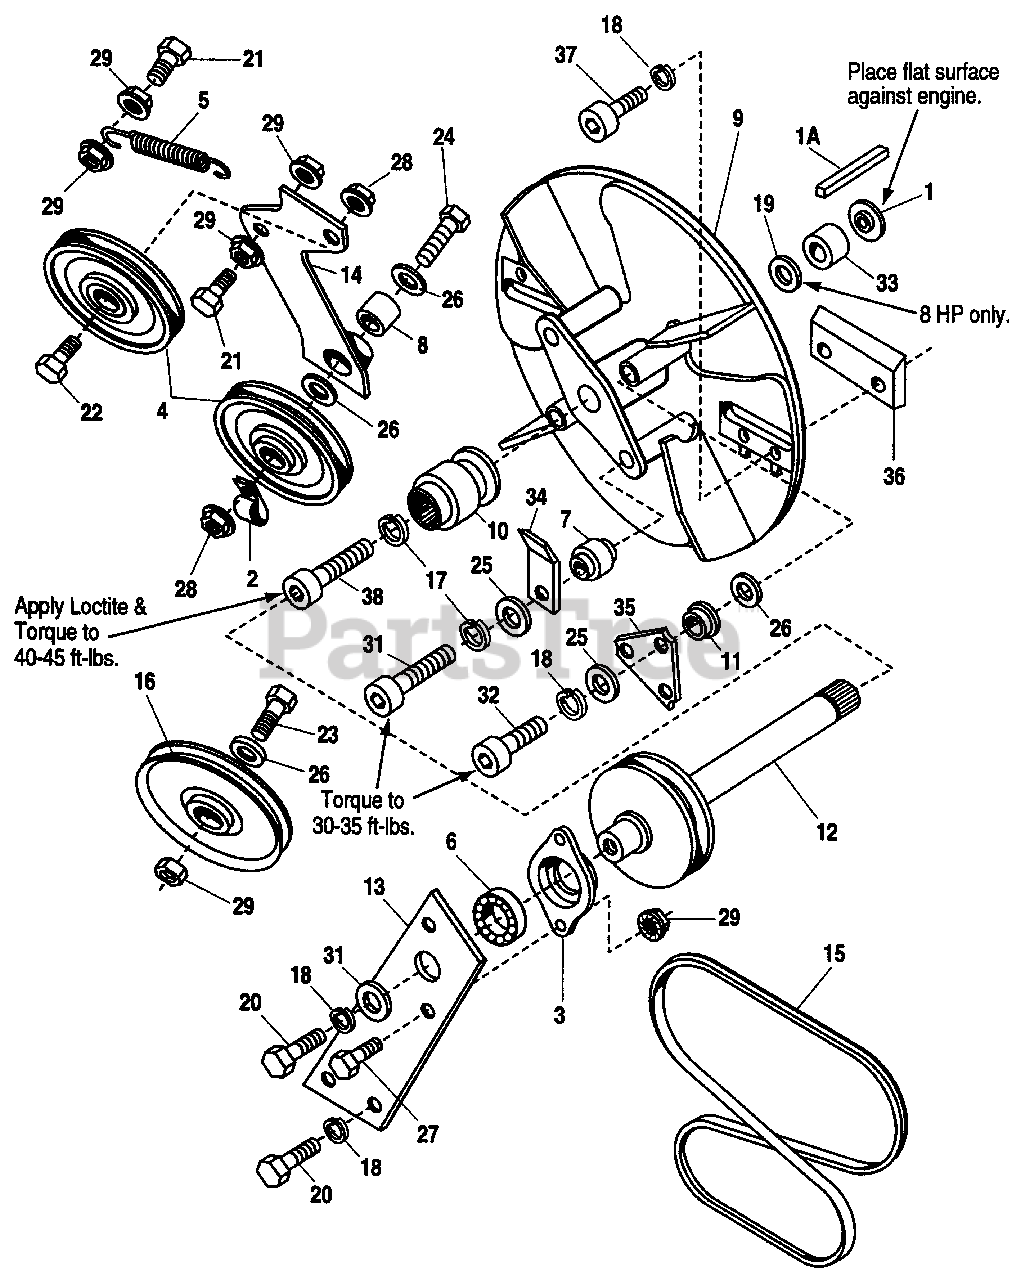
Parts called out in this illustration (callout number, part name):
1A	KEY, 1/4 sq. x 2-1/4
2	CLAMP, Cable
3	RETAINER, Bearing
4	IDLER PULLEY, "V"
6	BALL BEARING
8	SPACER, Tube
9	ROTOR ASSY.
11	BUSHING, Flanged
12	SHAFT ASSY.
13	PLATE, Bearing
14	IDLER ARM ASSY.
15	V-BELT, 60"
16	IDLER PULLEY, Flat, 4"
17	LOCKWASHER, 3/8
18	LOCKWASHER, 5/16
19	WASHER (8 HP models only)
20	CAPSCREW, Hex Hd., 5/16-18 x 3/4
21	CAPSCREW, Hex Hd., 5/16-18 x 1
22	CAPSCREW, Hex Hd., 3/8-16 x 1-1/2
23	CAPSCREW, Hex Hd., 3/8-16 x 1-3/4
24	CAPSCREW, Hex Hd., 3/8-16 x 2-3/4
25	WASHER, 3/8
26	WASHER, Flat 3/8
27	CAPSCREW, Hex Hd., 5/16-18 x 5/8
28	NUT, Hex, Flange "C" Lock, 3/8-16
29	NUT, Serrated, Flange Lock, 5/16-18
30	WASHER, 5/16
31	CAPSCREW, Hex, Socket Hd., 3/8-16 x 2
32	CAPSCREW, Hex, Socket Hd., 3/8-16 x 1-1/4
33	SPACER (Used on 5 HP models only)
35	* HAMMER, Triangle
36	KNIFE, Chipper
37	CAPSCREW, Hex, Socket Hd., 5/16 x 5/8
38	CAPSCREW, Hex, Socket Hd., 3/8-24 x 2
